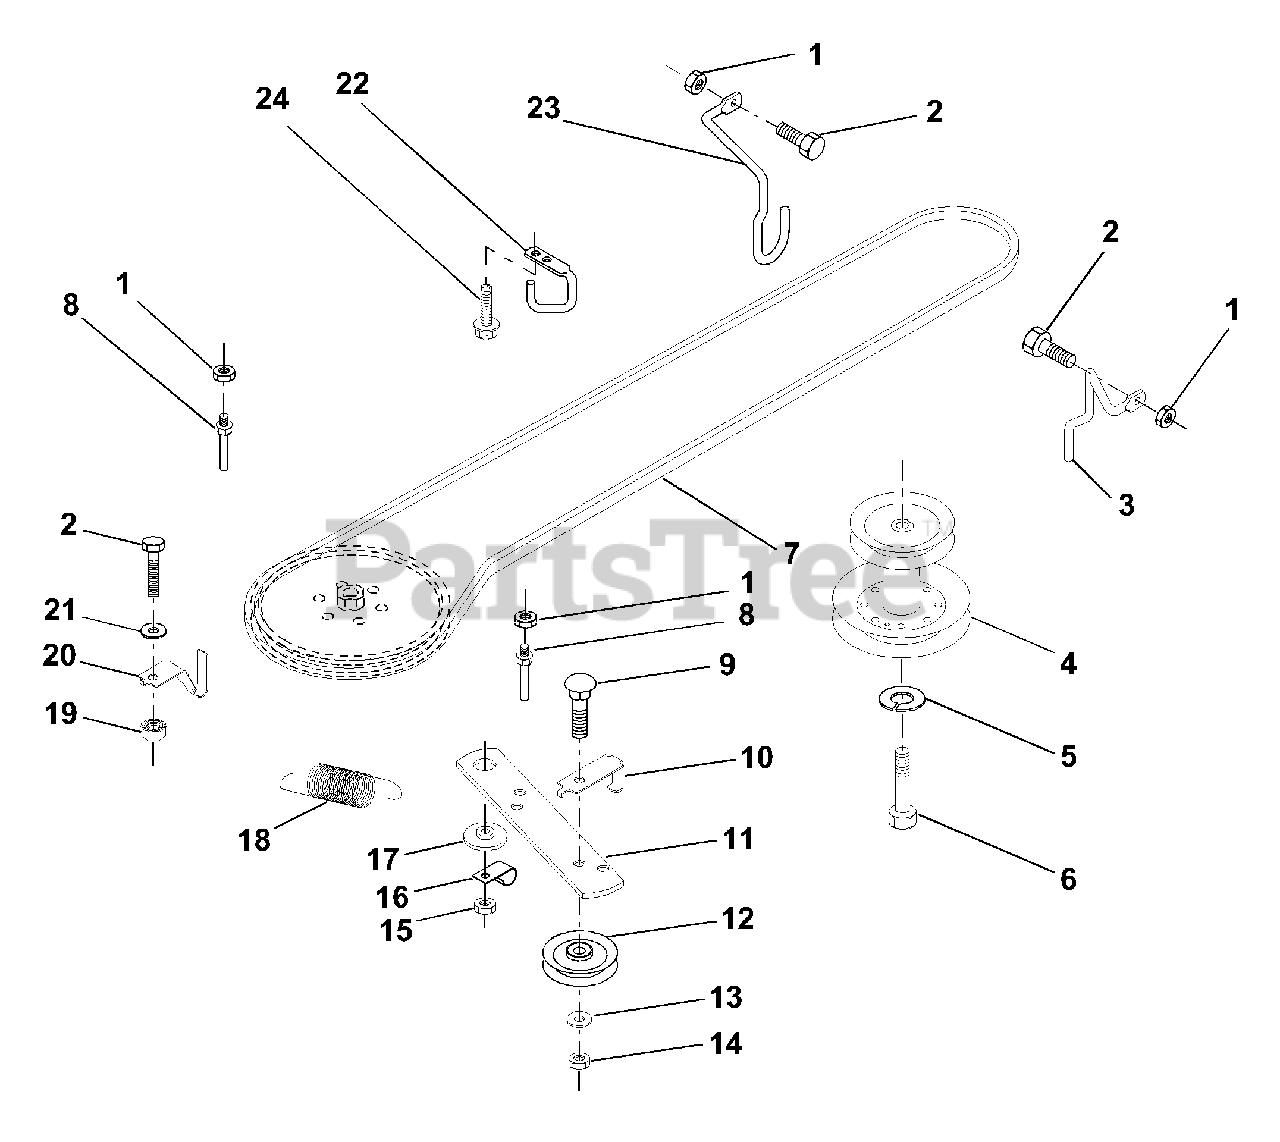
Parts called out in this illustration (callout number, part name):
1	Nut, Crownlock 5/16-18
2	Bolt, Hex Hd 5/16-18 UNC x 3/4
3	Keeper,Mower Drive, R. H.
4	Pulley, Engine
5	Washer, Lock 7/16
6	Bolt Hex 7/16-20 Gr. 5
7	Traction, V-Belt Drive
8	Keeper, T/A Ground Drive Belt
9	Bolt, Carr. 3/8-16 UNC x 1-1/2
10	Keeper, Belt Ground Drive Idler
11	Arm, Ground Drive Clutch
12	Idler, Flat
13	Washer 13/32 x 13/16 x 16 Ga.
14	Nut, Centerlock 3/8-16 UNC
15	Nut, Crownlock 3/8-16 UNC
16	Clip, Insulated
17	Spacer, Retainer
18	Spring Extension
19	Nut, Keps 5/16-18 UNC
20	Keeper, T/A Ground Drive Belt
21	Washer 11/32 x 5/8 x 16 Ga.
22	Keeper, Frame Ground Drive Belt
23	Keeper, Mower Drive, L. H.
24	Screw, Thd. Cut 1/4-20 x 1/2
